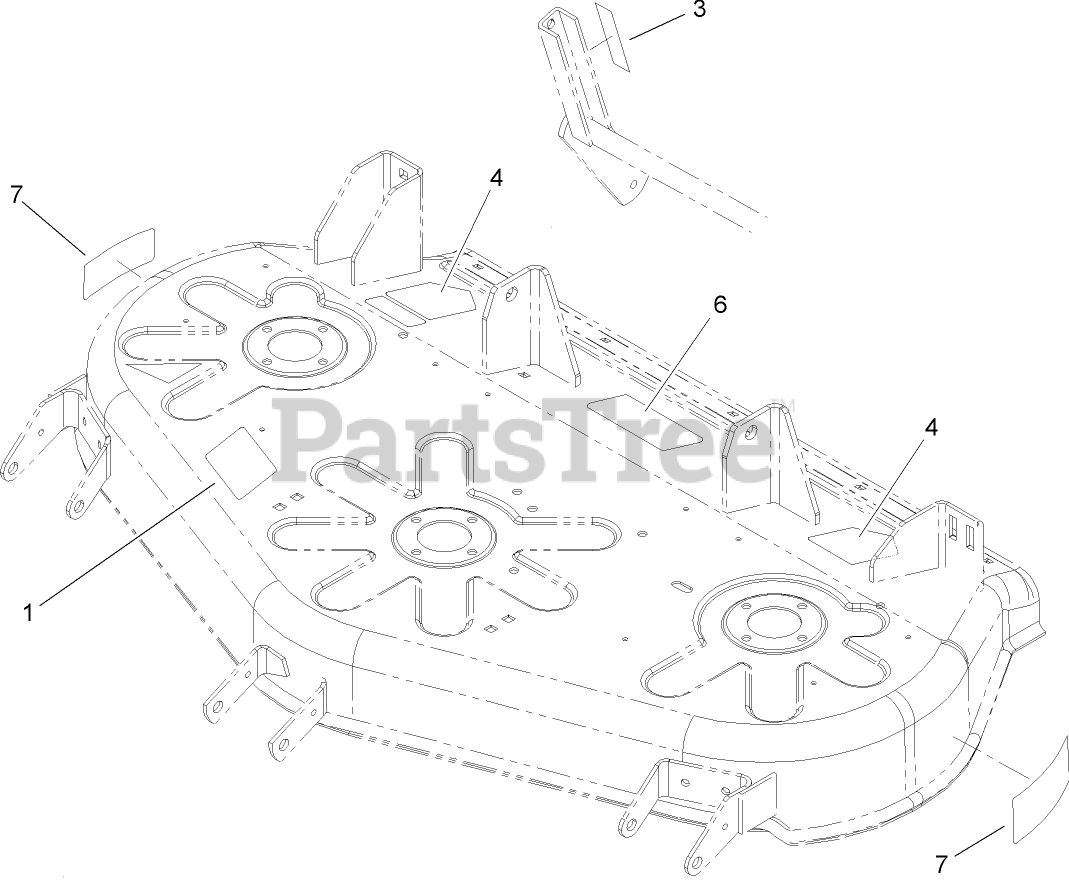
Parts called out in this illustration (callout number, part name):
1	DECAL-BELT ROUTING, PTO
3	DECAL-HOC
4	DECAL-DANGER
6	DECAL-BELT ROUTING
7	DECAL-DANGER
